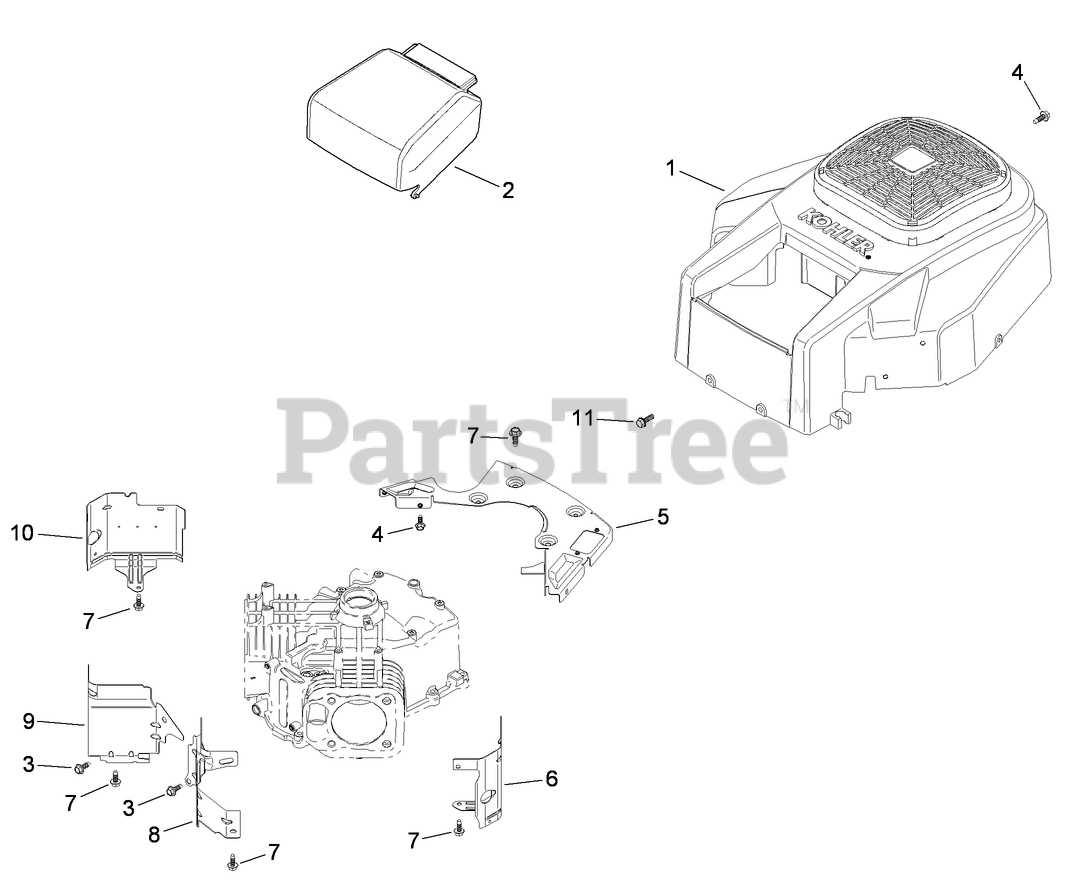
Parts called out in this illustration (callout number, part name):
1	BLOWER HOUSING ASM (FIXED GUARD) (INCLUDES 2, 3)
2	COVER-CLEANER, AIR (BLACK)
3	SCREW-HHFTF (M5X.80X10)
4	SCREW-FLANGE, THREAD FORMING (M5X0.8X16)
5	PLATE-BACKING
6	BAFFLE-BARREL, CYLINDER (No.2 SIDE)
7	SCREW-FLANGE, THREAD FORMING (M6X1.0X16)
8	BAFFLE-VALLEY (No.2 SIDE)
9	BAFFLE-VALLEY (No.1 SIDE)
10	BAFFLE-BARREL, CYLINDER (No.1 SIDE)
11	SCREW-TAP (M6X1.7X18)
